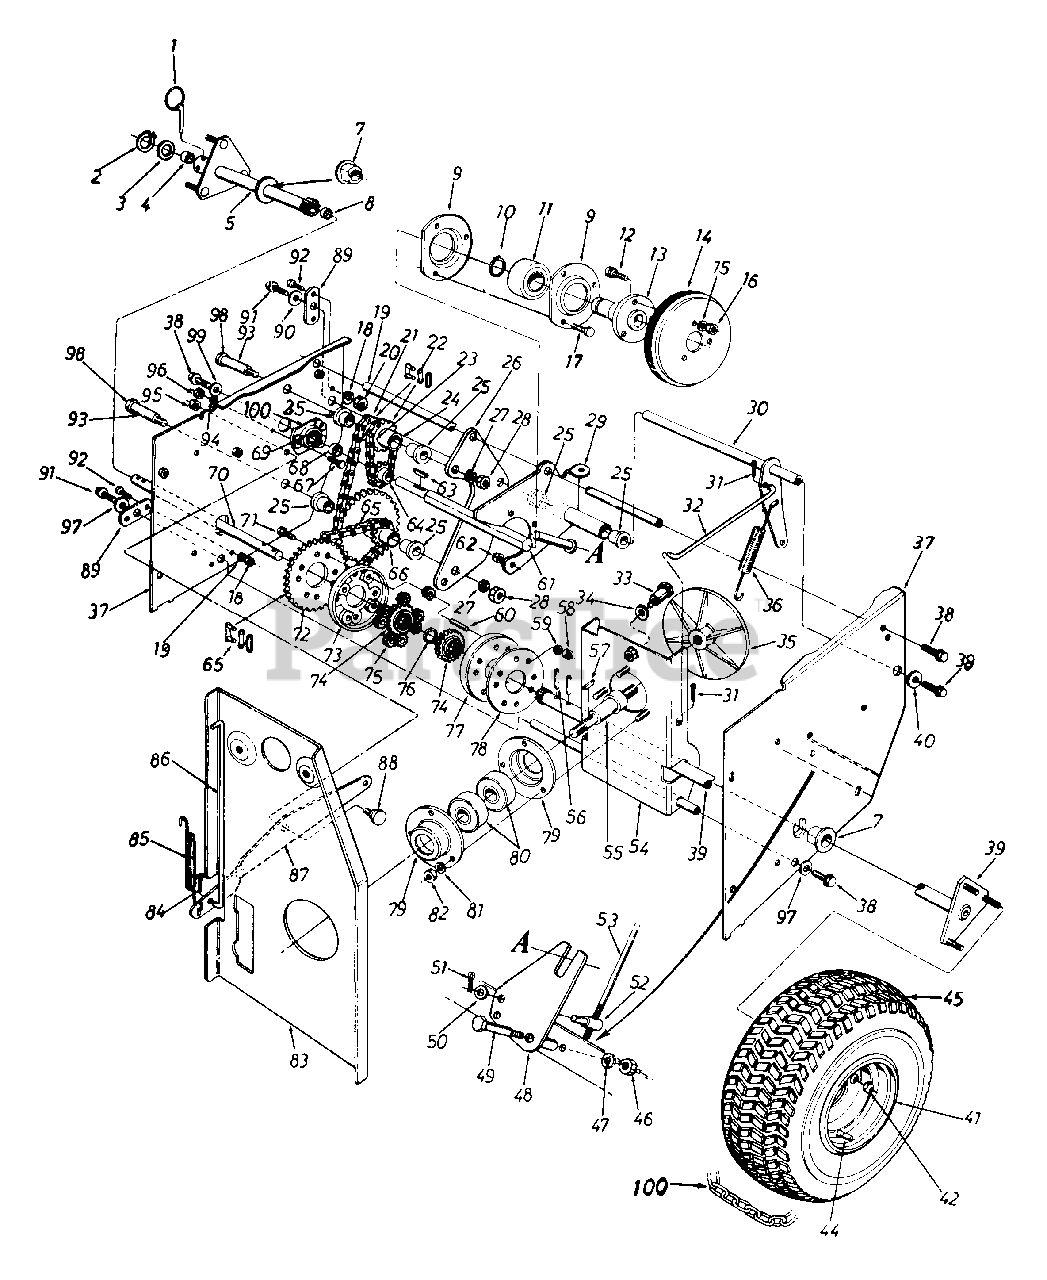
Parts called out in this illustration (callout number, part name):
1	Klick Pin 1/4" Dia. x 1.75"
2	Snap Ring .625" Shaft
3	Fl-Wash. .62" I.D. x 1.25"
4	Sleeve Brg.
5	Differential Tubing Ass'y.- R.H.
7	Flange Brg. w/Flats 1" I.D.
8	Sleeve Brg.
9	Bearing Housing
10	Snap Ring - 1.00" Dia.
11	Ball Brg. .25MM x 52MM x 15MM Thk.
12	Hex Sems Bolt 5/16-18 x .75" Lg.
13	Friction Wheel Adapter
14	Friction Wheel Ass'y.
15	L-Wash. 5/16" I.D.
16	Hex Nut 5/16-18 Thd.
17	Hex Bolt 1/4-28 x .62" Lg.
18	L-Wash. 1/4" I.D.
19	Sliding Support Axle
20	Hex Nut 1/4-20 Thd.
21	#41 Chain - 1/2" Pitch x 43 Links
22	Master Link
23	#41 Chain - 1/2" Pitch x 19 Links
24	9 and 14 Teeth Sprocket Hub Ass'y.
25	Flange Brg. .630" I.D.
28	Hex L-Jam Nut 3/8-24 Thd.
29	Sliding Brkt. Ass'y.
30	Drive Clutch Brkt. Ass'y.
31	Inter. Cot. Pin 5/16" Dia.
32	Drive Clutch Rod 7.38" Lg.
33	Shld. Bolt
34	Bell-Wash. .44" I.D. x.88"
35	Aluminum Drive Plate
36	Extension Spring 4.31" Lg.
37	Frame Ass'y.
38	Hex L-Bolt 5/16-18 x .62"
39	Differential Shaft Ass'y.
40	Fl-Wash. .345" I.D. x .75"
41	Rim Only - 16"
42	Cone Nut 3/8-24 Thd.
44	Tubeless Air Valve
45	Wheel Ass'y. Comp. 16 x 6.5
46	Hex Jam Nut 3/8-16 Thd.
47	L-Wash. 3/8" I.D.
50	Fl-Wash. .344" I.D. x.62"
51	Cotter Pin 3/32" Dia. x .75"
52	Adjustment Ferrule
53	Shifting Rod
56	H-Spring Pin Spiral 3/16" Dia. x 1.25" Lg.
57	#61 Hi-Pro Key 3/16 x 5/8" Dia.
58	Hex Nut 1/4-28 Thd.
59	L-Wash. 1/4" I.D.
60	Differential Pin
61	Hex Shaft
62	Hex L-Nut 1/4-28 Thd.
63	#9 Hi-Pro Key 3/32 x 5/8" Dia.
64	8 Teeth Sprocket
65	#420 Chain - .50 Pitch x 37 Link
66	9 and 32 Teeth Sprocket Hub Ass'y.
67	Hex Bolt 1/4-20 x .62" Lg.
68	Spacer .51" I.D. x .69" O.D.
69	Ball Bearing
70	Differential Connecting Shaft
71	Hex Bolt 1/4-28 x 1.75" Lg.
72	28 Teeth Sprocket
73	Differential Housing
74	20 Tooth Spur Gear
75	9 Tooth Spur Gear
76	Fl-Wash. .62" I.D. x 1.25"
77	Differential Housing
78	Differential Hsg. Support Plate
79	Bearing Housing
80	Ball Brg. .787" I.D. x 1.85"
81	L-Wash. 5/16" I.D.
82	Hex Nut 5/16-18 Thd.
83	Engine Brkt. Ass'y.
84	Inter. Cotter Pin 5/16" Dia.
85	Extension Spring 3.18" Lg.
86	Auger Clutch Rod .31" Dia. x 10.62" Lg.
87	Auger Clutch Brkt.
88	Shld. Bolt .625" Dia. x .170"
89	Pivot Axle Brkt.
90	Fl-Wash. .345" I.D. x.75"
91	Hex L-Bolt 5/16-18 x .62"
92	Hex Bolt 1/4-20 x .62" Lg.
93	Sprocket Hub Tubing 1.88"
94	L-Wash. 1/4" I.D.
95	Hex Cent. L-Nut 3/8-16 Thd.
96	Hex Nut 1/4-20 Thd.
97	Fl-Wash. .344" I.D. x .875"
98	Hex Bolt 3/8-24 x 2.75" Lg.
99	Bell-Wash. .345" I.D. x .88"
100	Tire Chain
